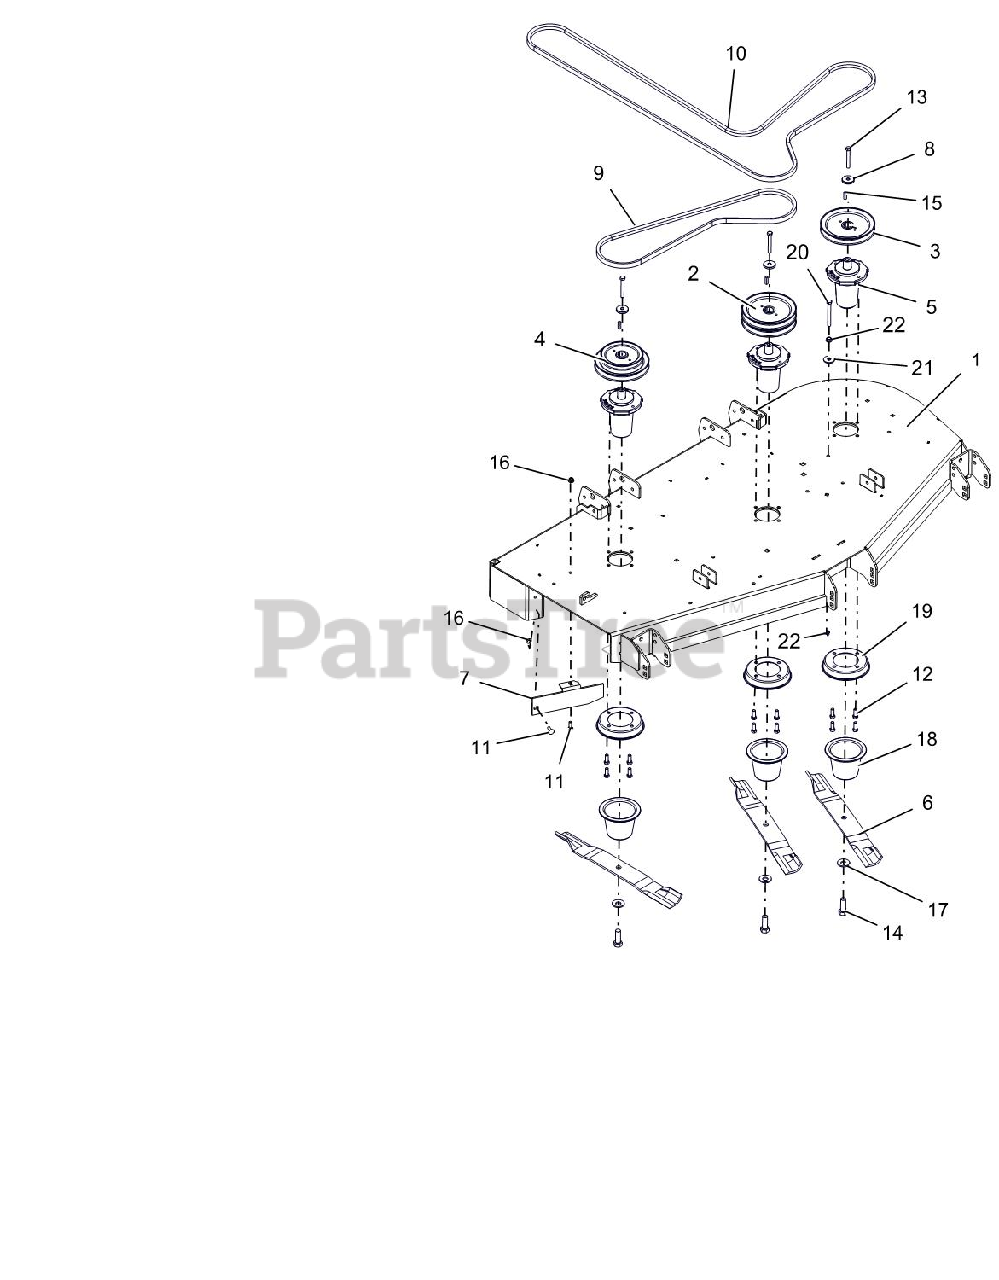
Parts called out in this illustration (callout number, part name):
1	DECK, PT160 W/SAFETY DECALS
2	PULLEY, DOUBLE-1"ID X 6.75"OD
3	PULLEY, V-1" ID X 6.75" OD
4	PULLEY, DBL-1"IDX6.75"&5.25"OD
5	ASM, MAINT FREE SPINDLE
6	BLADE, MOWER (20.50")
7	60" DISCHARGE BAFFLE - RED
8	RETAINER, SHEAVE
9	V-BELT, B-COGGED
10	BELT, B-SECTION EPDM RAW EDGE
11	@BLT-RDHDSQNK .31-18X1.00 G5YZ
12	BLT-HEX .38-16X1.0 GR8 YZ EP30
13	BLT-HEX .38-16X2.75 GR8 YWZC
14	BLT-HEX .62-18X1.75 GR8 YWZC
15	KEY, SQ .25X.25X1.00 RC 40-50
16	@NUT-LK-NYL-FLG .31-18 YWZC
17	WSHR-BLVL .669X1.535X.138
18	GUARD, SPINDLE LOWER
19	GUARD, SPINDLE TOP
20	@BLT-HEX .38-16X3.50 GR5 YWZC
21	WSHR-FL-STL .406X1.375X.135 YZ
22	@NUT-SPNLK-FLG .375-16 YWZC
